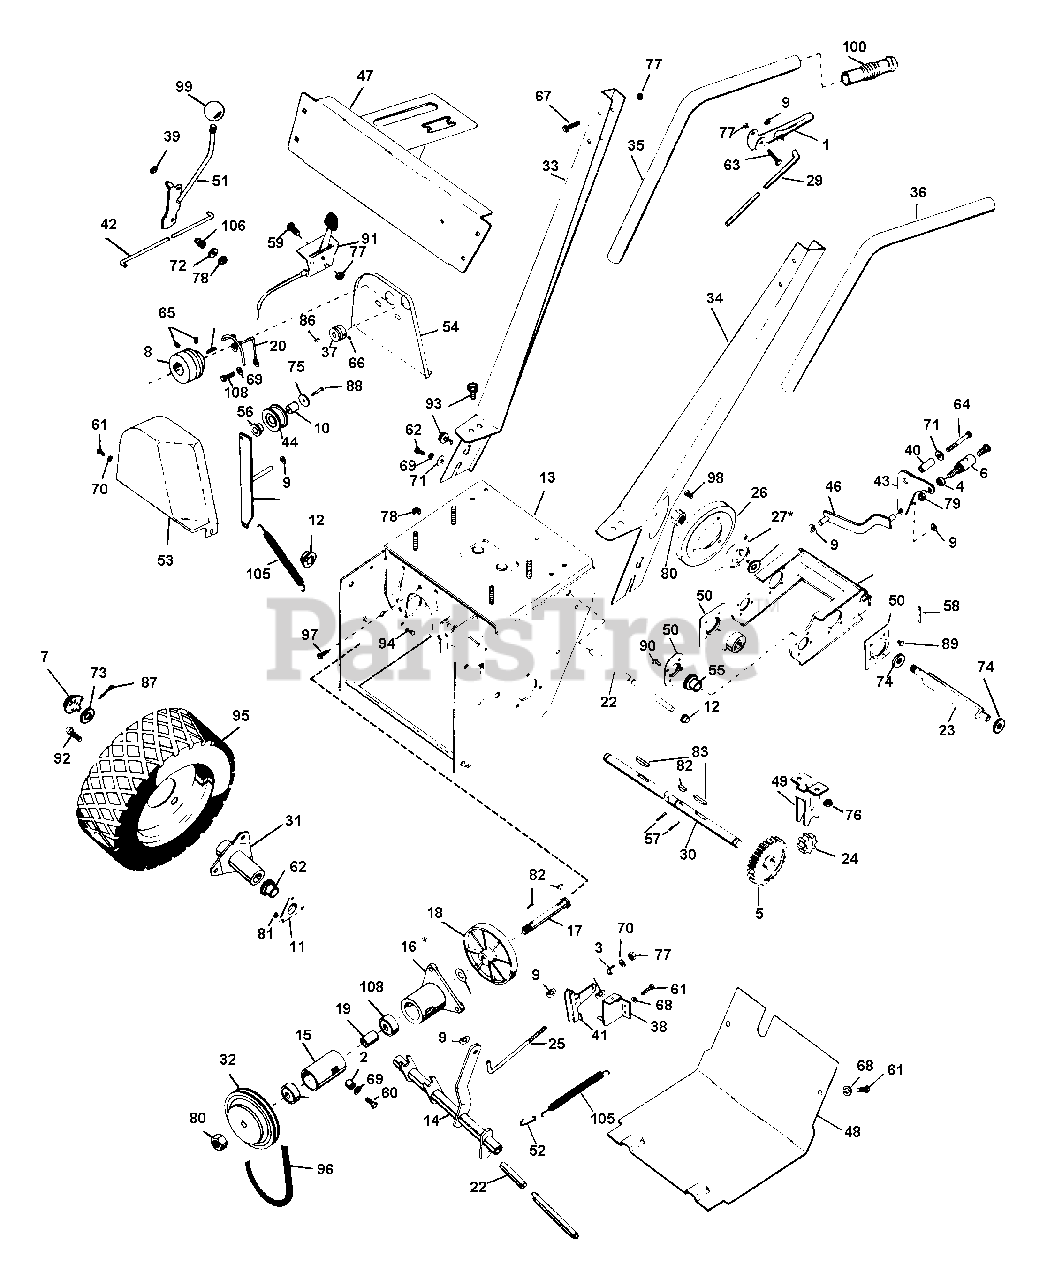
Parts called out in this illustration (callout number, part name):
1	CLUTCH HANDLE
4	SPACER BUSHING .5 X .32 X .21
5	SPUR GEAR, FELLOWS 35T .750 ID
6	BALL JOINT
7	HUB CAP
8	ENGINE SHEAVE
9	RATCHET PLATE
10	IDLER SHFT
11	SUPPORT, BEARING
12	CAP, .50 ROD YWZC
13	TRACTOR FRAME
15	SPINDLE HOUSING
16	DRIVE SPINDLE HOUSING
17	SPINDLE
18	DRIVE DISK
19	BEARING SPACER .75 X .5 X.88
20	BELT FINGER
21	CARRIER
23	HEX SHAFT
25	ADJUSTMENT LINK
26	FRICTION DISC
27	FRICTION DISC HUB
28	BEARING RETAINER
29	CLUTCH LINK
30	AXLE SHAFT
31	WHEEL HUB
32	DRIVE SHEAVE
33	R H LOWER HANDLE BAR
34	L H LOWER HANDLE BAR
35	R H UPPER HNDLBR
36	L H UPPER HNDLBR
37	CAM SHAFT SHEAVE
38	DEADMAN BRACKET
39	SPRINGGRIP FASTENER
40	BSHG-SLV .334 X .502 X 1.437
41	DEADMAN LEVER
42	SHIFT ROD
43	SHIFT LEVER
45	IDLER ARM
46	SHIFT LINK
47	HANDLE BAR BRACKET
50	BEARING RETAINER
51	SHIFT HANDLE
52	SPRING HOOK
53	OUTER BELT COVER
54	INNER BELT COVER
55	BSHG-FLG .750X1.000X.625X1.250
56	BSHG-FLG .500X.625X.500X.750
57	PIN-ROLL .125X1.00
58	PIN-ROLL .188X1.00
59	BLT-HEX .25-20X.75 PL GR2
60	BLT-HEX .31-18X1.00 PL GR 2
61	BLT-HEX .25-20X.50 PL GR2
62	BLT-HEX .31-18X.50 PL GR2
63	BLT-HEX .25-20X1.50 PL GR5
64	BLT-HEX .31-18X2.00 PL GR2
65	SCR-SET .32-18X.38 SKHCUPNL OH
66	SCR-SET .25-20X.25 SKHCUPNY OH
67	BLT-RDHDSQNK .25-20X1.50 SHTPL
68	WSHR-LK .250X.077 HVY PL
69	WSHR-LK .312X.097 PL HVY
70	WSHR-FL-STL .250X.562X.049 PL
71	WSHR-FL-STL .38X.875X.083 PL
72	WSHR-FL-STL.312X.734X.065PL
73	WSHR-FL-STL .755X2.000X.125
74	WSHR-FL-STL .505X1.000X.062
75	WSHR-FL-STL .192X.937X.062
76	NUT-LK-CTR .625-18 PL
77	NUT-LK-CTR .250-20 PL
78	NUT-LK .312-18 GR A PL
79	NUT-LK-CTR .312-24 PL
80	NUT-LK-CTR .50-20 PL
81	NUT-LK-FLG .250-20 PL
82	KEY-WDRF .125X.500X.203 SAE 3
83	KEY-FTHR .188X1.25X.187 SAE
84	KEY-WDRF .25X.750X.313 SAE91
85	KEY-SQ .188X1.0X.188 SAE 8630
86	KEY-WDRF .125X.625X.250 SAE5
87	PIN-COTR .12 X 1.25 PL
88	RVT .187 X .781 OH ST PL
89	RVT-POP .187X.402 DOME ST
90	RVT-POP.125 X .294 DOME
91	THROTTLE CONTROL
92	BLT-WHL .50-20X.50 GR5 PL
93	BLT-SERHFWH .31-18X.50 PL
94	SCR-SLTR-SERNK .25-20X.62 PL
95	WHL 10.25 IN O.D.
96	V-BELT, SPECIAL-RAW EDGE (SET)
97	SCR-TAP .312-18X.50 HWH PL TR
98	SCR-TAP .250-20X.37 HWH PL TR
99	SHIFT BALL
100	GRIP
101	4 HP ENGINE DECAL
102	CAUTION DECAL
103	SHIFT DECAL
104	HANDLEBAR DECAL
105	SG-TENS .063X.44X2.81 WLD 18
106	SG-COMP .092X.375X2.53
